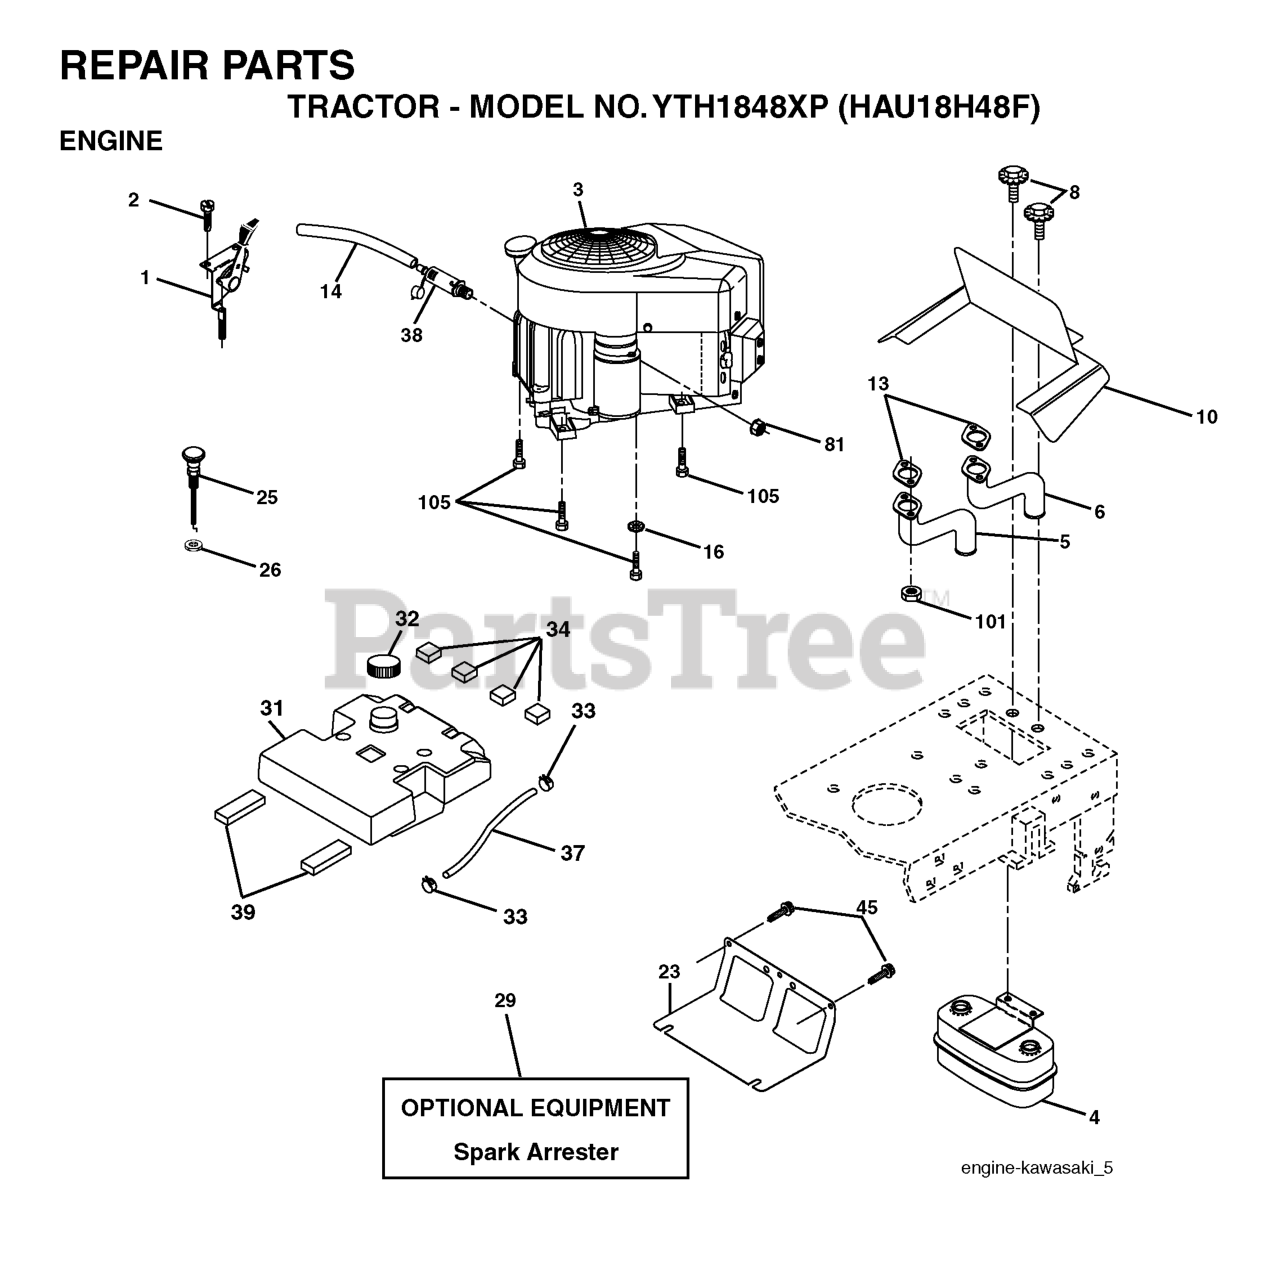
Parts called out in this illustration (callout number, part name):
1	CONTROL, THROTTLE
2	SCREW
4	MUFFLER.TWIN.CYL.LOW.TONE
5	EXHAUST.TUBE.LH.KAWASAKI.
6	EXHAUST.TUBE.RH.KAWASAKI.
8	BOLT.5/16-18UNCX3/4 W/SEMS.BLK
10	RP SHIELD HEAT MUFFLER
14	TUBE, DRAIN OIL ASM.
16	LOCKWASHER
23	SHIELD.BROWNING.DBR.GUARD
25	CHOKE CONTROL
26	Nut Keps 3/8 - 24 UNF
29	KIT.SPARK ARRESTOR 794945 B&S
31	TANK.FUEL(3.5.GAL)
32	FUEL CAP
33	HOSE CLAMP
34	PAD-SPACER LT
37	REPL BY 532 00 85-43
39	PAD IDLER TI
45	SCREW, 3/8-16X3/4
81	NUT
101	NUT.HEX.FLANGE.TOPLOCK
105	SCREW 3/8-16X1
